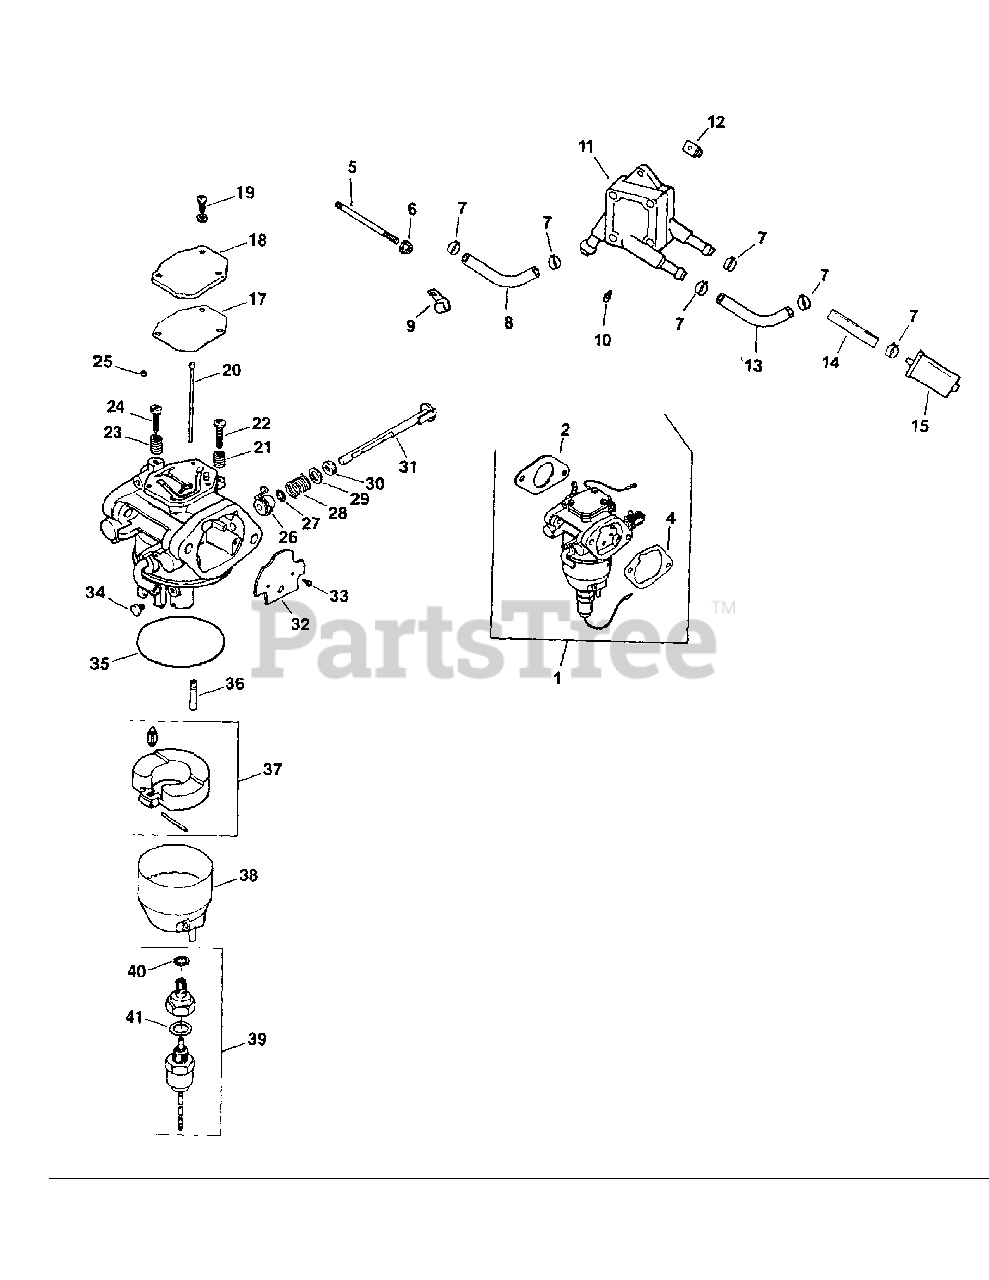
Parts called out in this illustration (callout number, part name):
1	Kit, Carburetor w/Gaskets
2	Gasket, Carburetor
4	Gasket, Air Cleaner Base
5	Stud
6	Nut, Hex Flange
7	Clamp, Hose
8	Line, Fuel 10-1/2"
9	Clip, Cable
10	Screw, Hex Cap
11	Pump, Fuel-Pulse
12	Nut, Plastic
13	Line, Fuel 11-1/2"
14	Line, Fuel 3-1/2"
15	Filter, Fuel
17	Gasket, Passage Cover
18	Cover, Passage
19	Screw, Sems Pan Head
20	Jet, Slow
21	Spring, Idle Adjusting Screw
22	Screw, Idle Adjusting
23	Spring, Throttle Adjusting Screw
24	Screw, Throttle Adjusting
25	Jet, Air Bleed
26	Lever, Choke
27	Ring, Choke Lever
28	Spring, Choke Return
29	Collar, Choke
30	Washer, Felt
31	Shaft, Choke
32	Plate, Choke
33	Screw, Sems Pan Head
34	Jet, Main
35	Gasket, Float Chamber
36	Nozzle, Main
37	Kit, Float
38	Chamber, Float
39	Kit, Solenoid Valve
40	Gasket, Chamber Screw
41	Gasket, Solenoid
